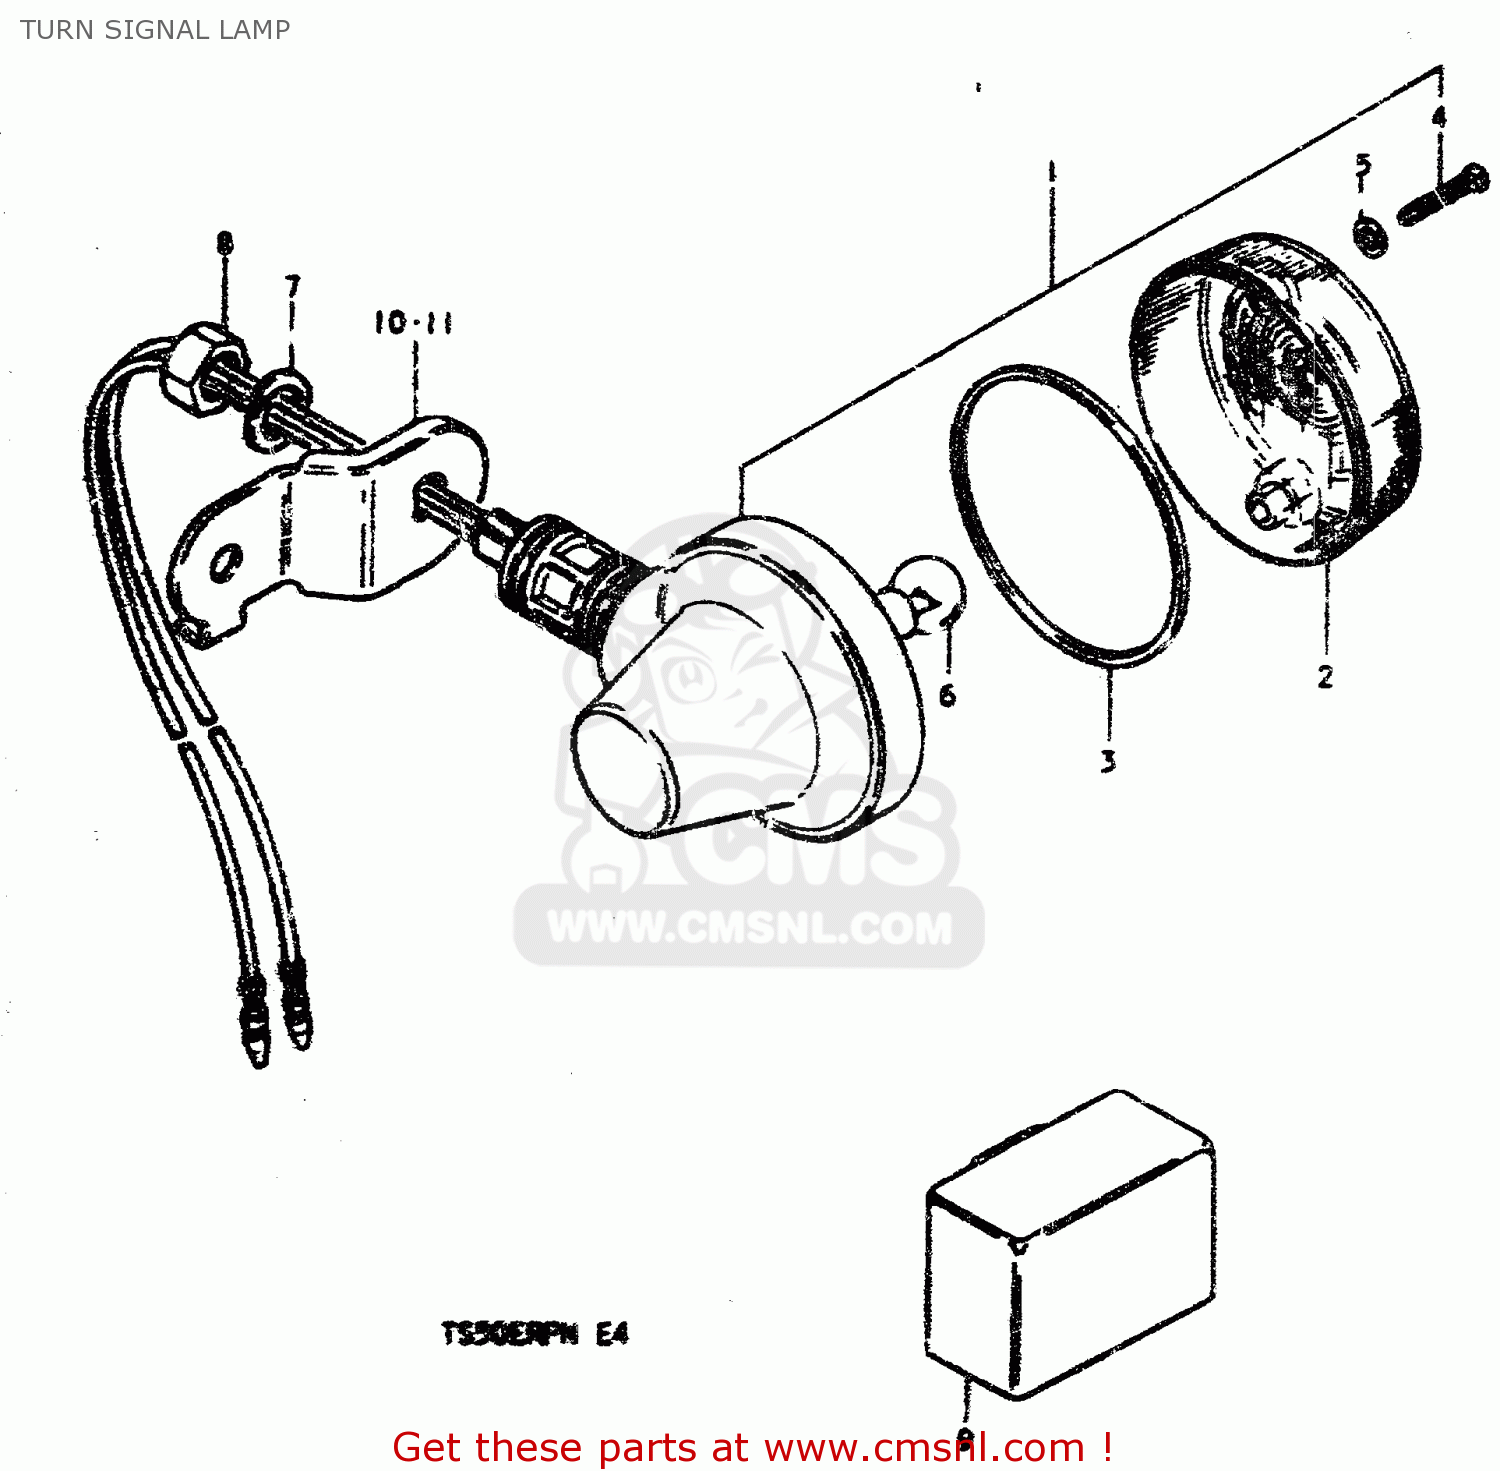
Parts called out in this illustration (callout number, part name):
1	LAMP ASSY, REAR TURN SIGNAL LAMP
2	LENS
3	GASKET (NAS)
4	SCREW TAPP.
5	GASKET (NAS)
6	BULB(6V/10W,STANLEY,A4117)
7	WASHER,LOCK 12
8	NUT
9	RELAY ASSY, TURN SIGNAL
10	BRACKET,REAR TURN SIGNAL
11	BRACKET,REAR TURN SIGNAL
